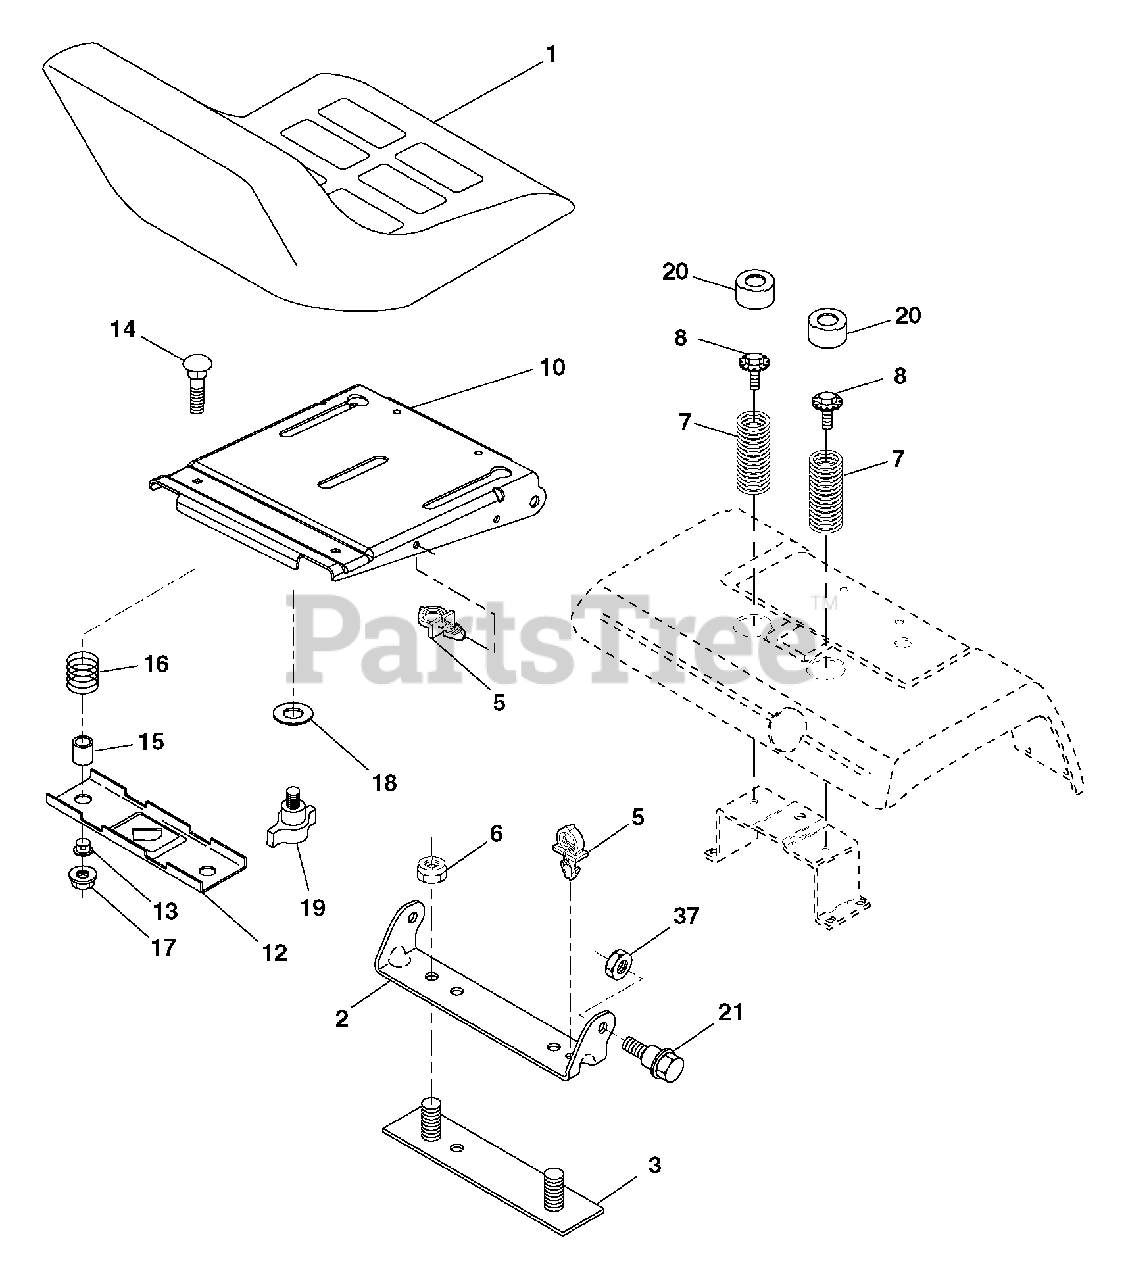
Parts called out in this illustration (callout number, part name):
1	Seat
2	Bracket, Pivot Seat
3	Strap Asm.
5	Clip, Push-In Hinged
6	Nut, Crownlock 3/8-16
7	Spring, Seat Cprsn.
8	Bolt 5/16-18 unc x 3/4 w/Sems
10	Pan, Seat
12	Bracket, Mounting Switch
13	Bushing, Snap
14	Bolt, Carriage 1/4-20 x 1-1/2
15	Spacer, Split
16	Spring, Cprsn.
17	Nut, Lock 1/4 Lg. Flg. Gr. 5
18	Washer 17/32 x 1-3/16 x 12 Ga.
19	Knob, Seat
20	Cap, Spring Seat Blk
21	Bolt 5/16-18 unc-2A
37	Nut, Crownlock 5/16-18
